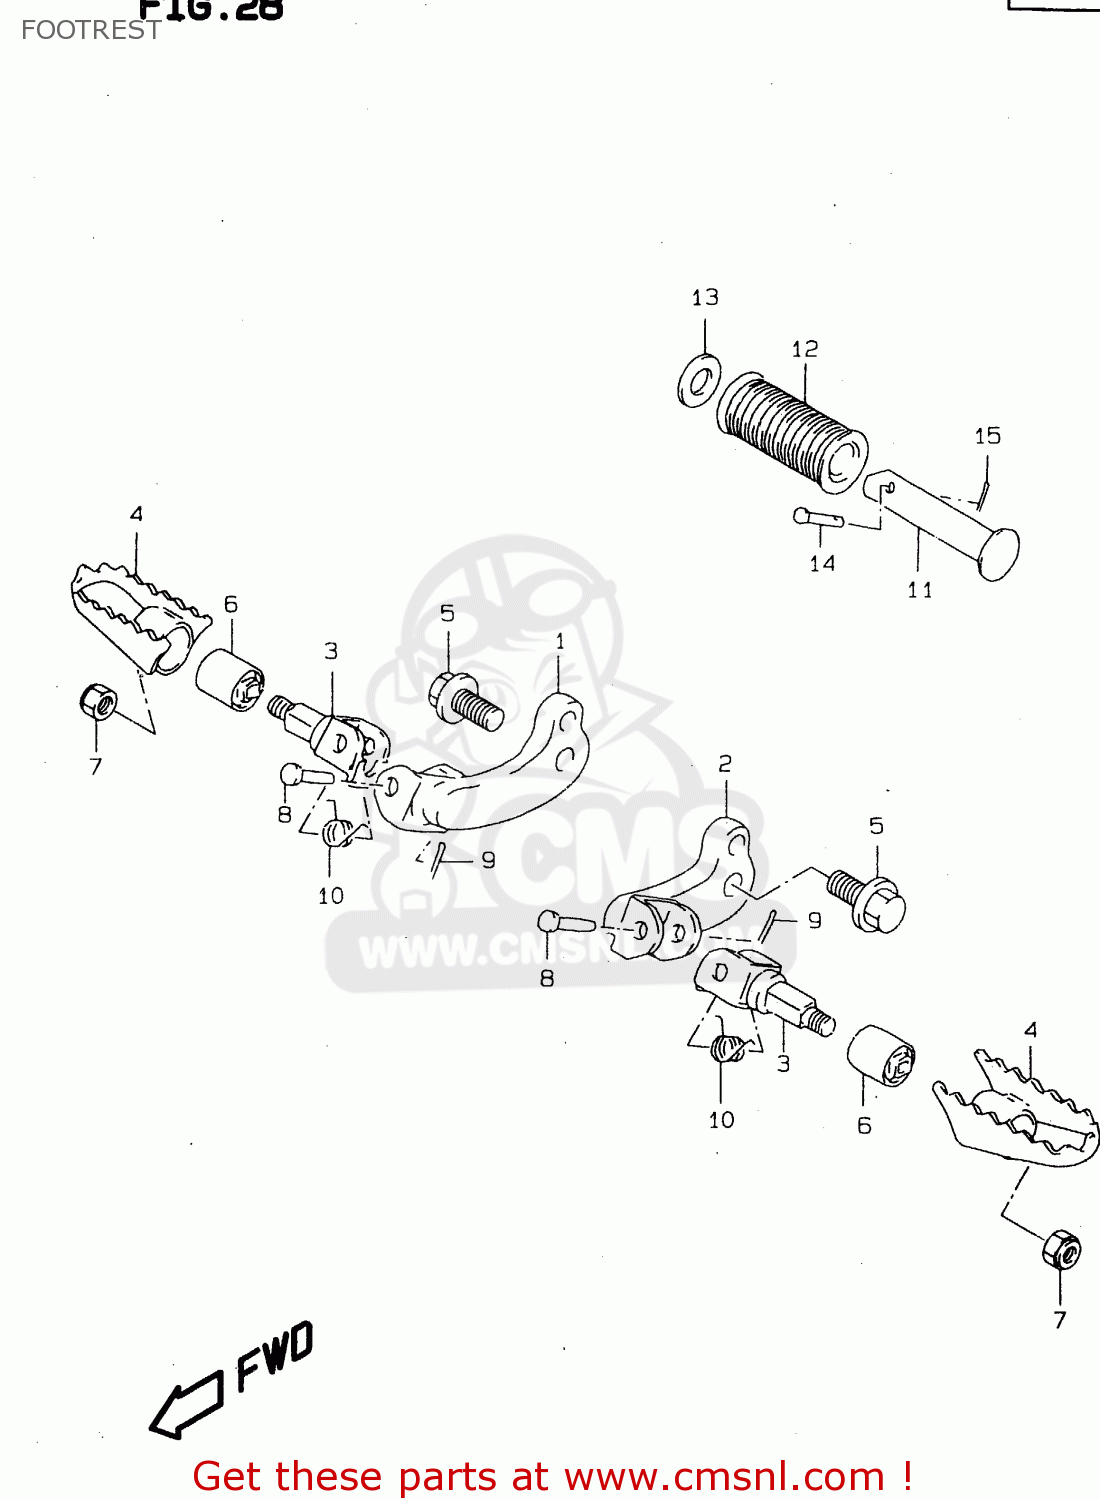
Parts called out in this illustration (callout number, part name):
1	BAR,FR FOOTREST,R
2	BAR,FR FOOTREST,L
3	BRACKET,FR FOOTREST
4	FOOTREST,FR
5	BOLT(12X25)
6	BUSH
7	NUT
8	PIN
9	PIN
10	SPRING
11	BAR,FOOTREST RUBBER
12	RUBBER,PILLION FOOTREST
13	WASHER(19.5X32X2)
14	PIN
15	PIN
